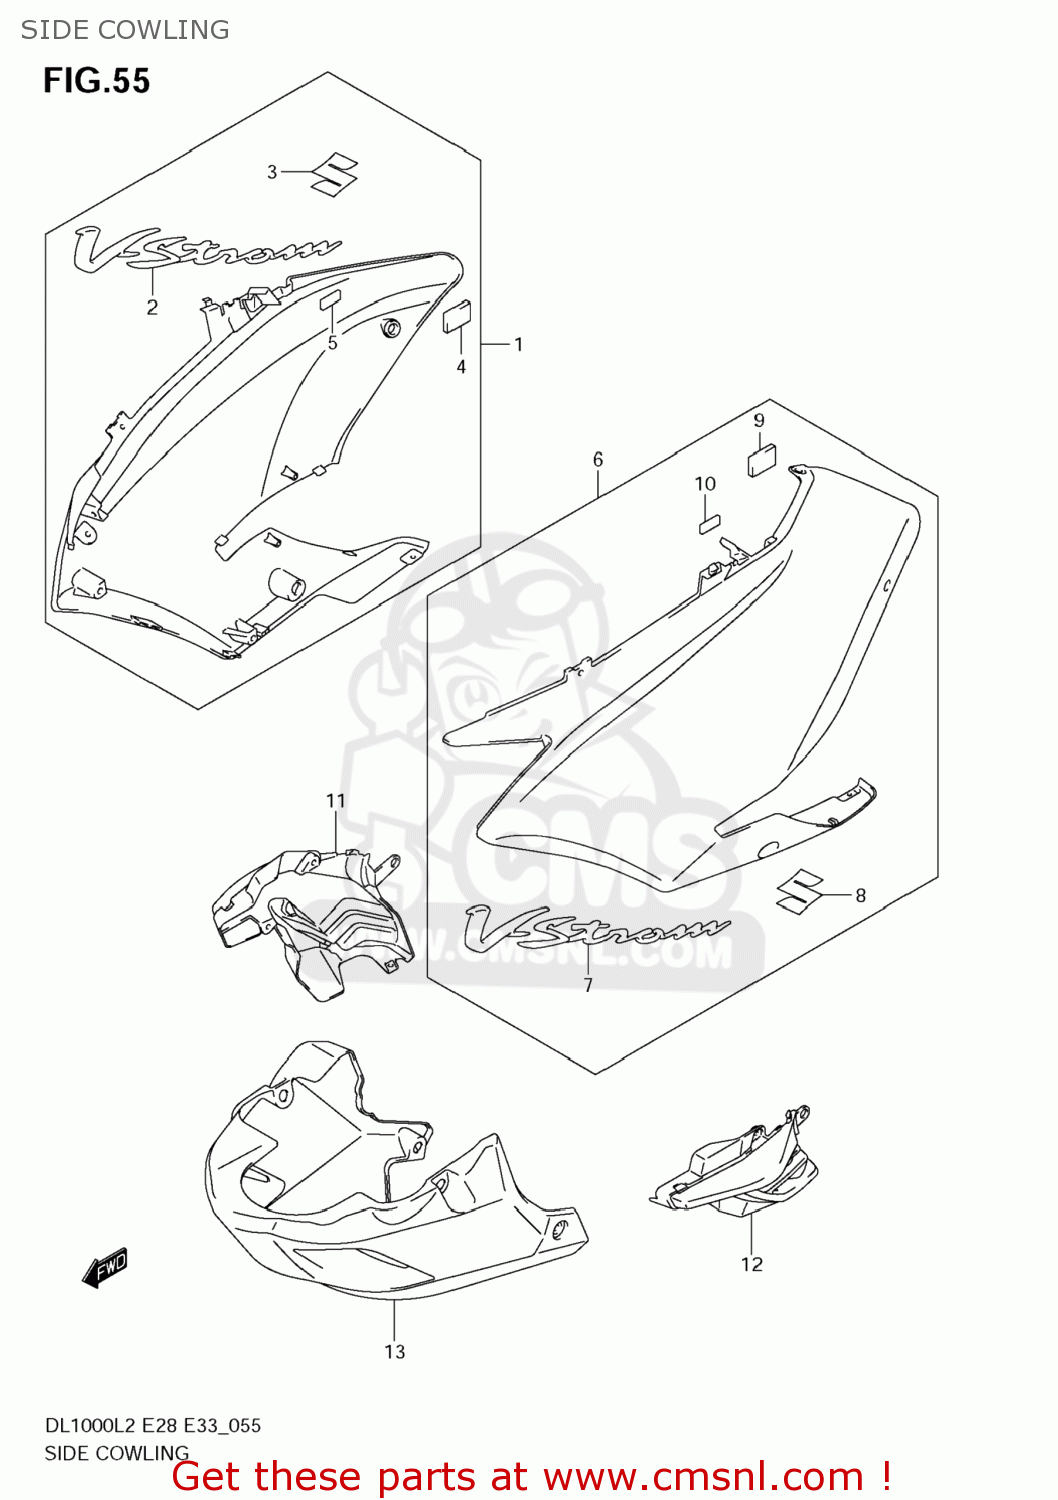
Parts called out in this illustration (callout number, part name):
1	COWLING ASSY,SIDE,R
2	EMBLEM,COWLING SIDE
3	EMBLEM,S
4	CUSHION
5	TAPE(6X25X0.13)
6	COWLING ASSY,SIDE,L
7	EMBLEM,COWLING SIDE
8	EMBLEM,S
9	CUSHION
10	TAPE(6X25X0.13)
11	COVER,SIDE COWL,R(BLACK)
12	COVER,SIDE COWL,L(BLACK)
13	COWLING,UNDER
